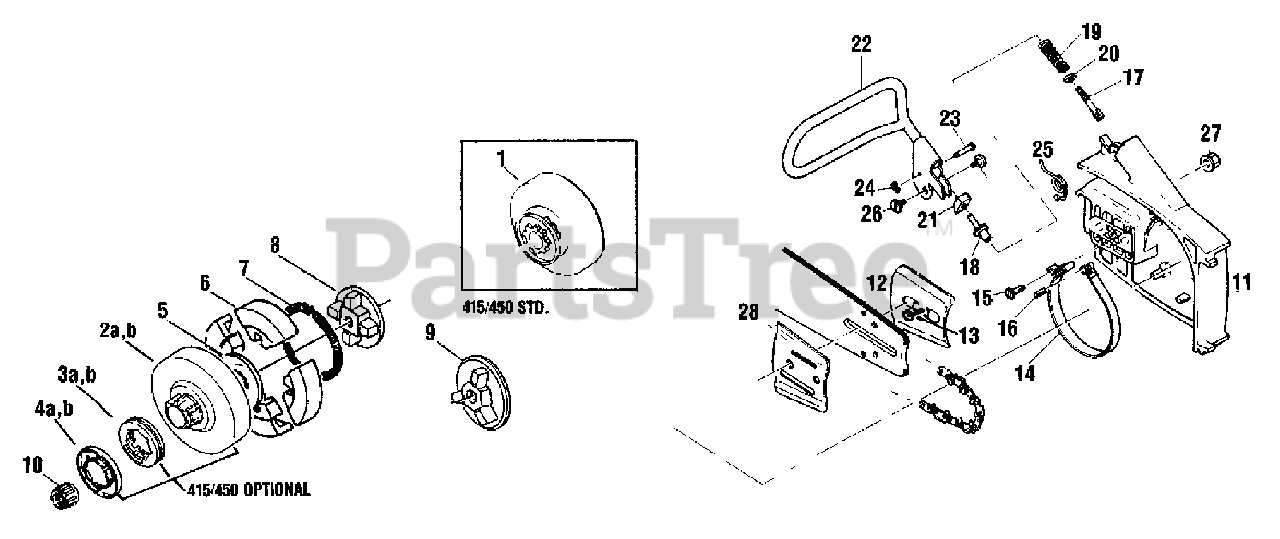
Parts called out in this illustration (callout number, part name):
1	DRUM, CLUTCH
2A	DRUM, CLUTCH
2B	DRUM, CLUTCH
3A	SPROCKET, RIM
3B	SPROCKET, RIM
4A	COVER, RING
4B	COVER, RING
5	HUB, CLUTCH
6	SHOE, CLUTCH
7	SPRING, CLUTCH
8	HUB, CLUTCH - OUTER
9	HUB, CLUTCH - OUTER
10	BEARING, NEEDLE
11	CLUTCH COVER ASSY
12	PLATE, GUIDE - OUTER
14	BAND, BRAKE
15	BOLT
16	PIN - SPRING
17	ROD, ADJUST
18	SCREW, ADJUST
19	SPRING, BRAKE
22	LEVER
23	PIN - STOPPER
24	RING, RETAINING
25	RELIEF SPRING
26	BOLT, LEVER
27	NUT
28	PLATE, GUIDE - INNER
